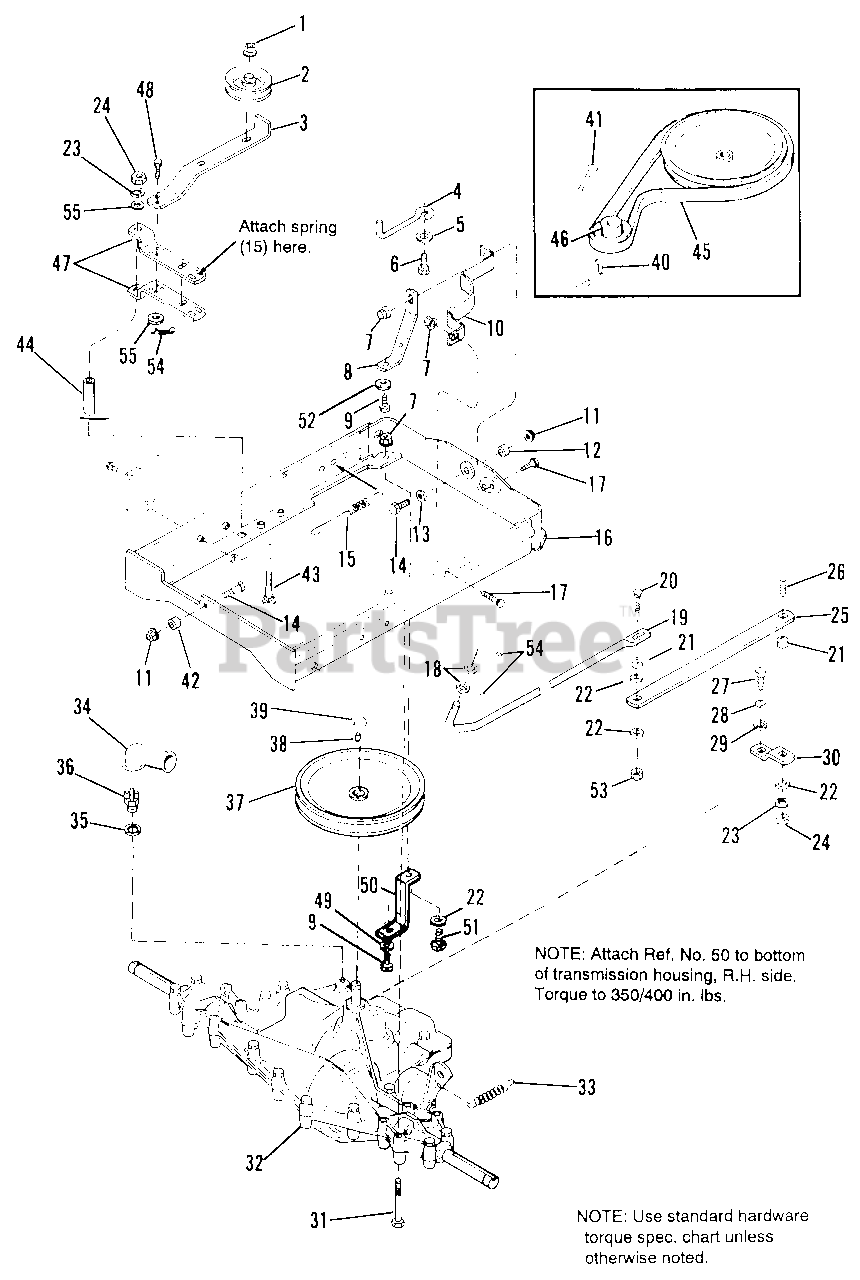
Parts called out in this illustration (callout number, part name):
1	NUT, Hex, Flange Lock, 3/8-16
2	PULLEY, Idler
3	LEVER, Idler, Pulley
4	BELT STOP
5	WASHER, Plain, 13/32 x 1 x 1/8
6	CAPSCREW, Hex Hd., 3/8-16 x 1-3/4
7	NUT, Hex, Flange, Whizlock, 5/16-18
8	STRAP, Torque
9	SCREW, Hex Hd., Taptite, 3/8-18 x 5/8
10	GUIDE, Belt, Transmission
11	NUT, Hex, Flange Lock, 1/2 x 13
12	BUSHING, Rear
13	WASHER, Plain
14	CAPSCREW, Hex Hd., 1/2-13 x 1-1/4
15	SPRING, Idler
16	CARRIER ASSY.
17	CARRIAGE BOLT, 5/16-18 x 5/8
19	ROD, Shift, Front
20	CARRIAGE BOLT, 5/16-18 x 1-1/4
22	WASHER, Plain, 5/16
23	LOCKWASHER, 5/16
24	NUT, Hex, 5/16-18
25	BAR, Shift, Rear
26	CARRIAGE BOLT, 5/16-18 x 1
27	SCREW, Hex Hd., 1/4-28 x 5/8
28	LOCKWASHER, 1/4
29	WASHER, Plain, 17/64 x 5/8 x 3/64
30	BRACKET, Shift
31	SCREW, Hex Hd., Taptite, 5/16-18 x 2-1/4
32	TRANSMISSION, 5-Speed (Gear)
33	SPRING, Brake, Return
34	COVER, Terminal
35	WASHER, Plain, 21/32 x 1-1/4 x 1/16
36	SWITCH, Ball
37	PULLEY ASSY., Driven, Transmission
38	KEY, Woodruff, #9
39	RING, Retaining
42	BUSHING, Front
43	CARRIAGE BOLT, 5/16-18 x 2-3/4
44	SPACER, Pivot
46	PULLEY ASSY., Drive, Engine
47	CLEVIS, Idler, Bracket
48	SCREW, Hex Hd., Flange, Taptite, 1/4-20 x 5/8
49	WASHER, Plain, 7/16 x 1-1/4 x 1/8
50	STRAP, Torque
51	SCREW, Hex, Flange, Whizlock, 5/16-18 x 3/4
52	WASHER, Plain, 13/32 x 7/8 x 5/64
53	NUT, Hex, Nylon Lock, 5/16-18
54	COTTERPIN, 3/32 x 3/4
55	WASHER, Plain
